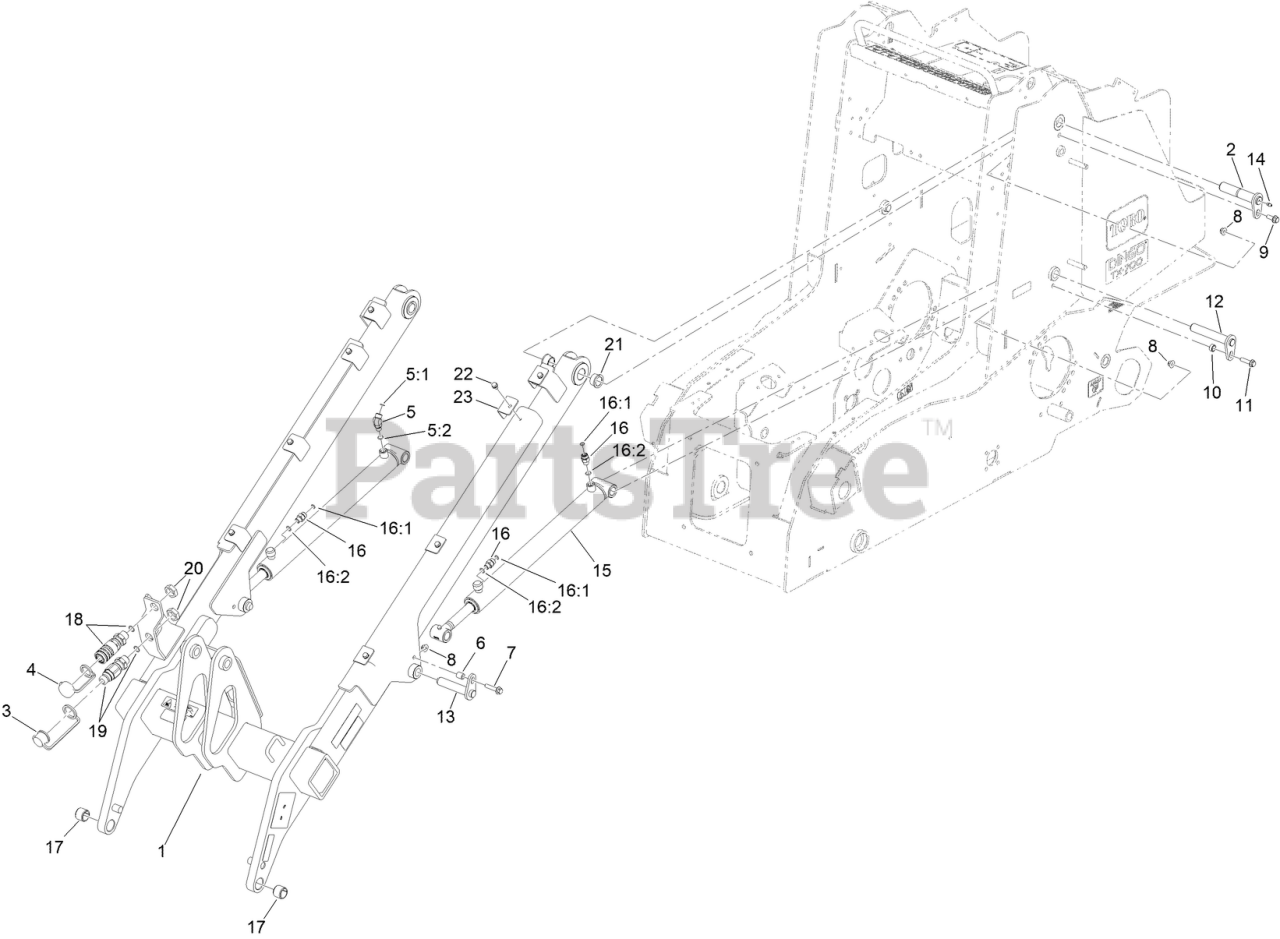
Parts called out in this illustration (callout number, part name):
1	LOADER ARM ASM
2	PIN-FLAG
3	CAP-DUST, NIPPLE
4	CAP-DUST, COUPLER
5	FITTING-ELBOW, 45 DEG
5:1	O-RING
5:2	O-RING
6	SPACER
7	SCREW-HHF
8	NUT-HF, NI
9	SCREW-HHF
10	TUBE-SPACER
11	SCREW-HHF
12	PIVOT PIN ASM (WELDED)
13	PIVOT PIN ASM (WELDED)
14	FITTING-GREASE
15	CLY-HYD
16	FITTING-STRAIGHT
16:1	O-RING
16:2	O-RING
17	BUSHING-TENSION
18	COUPLER ASM,BULKHEAD,
19	COUPLER ASM,BULKHEAD,
20	NUT-LOCK, BULKHEAD
21	BUSHING-FLANGE
22	SCREW-HWH
23	PLATE-RETAINER, HOSE
